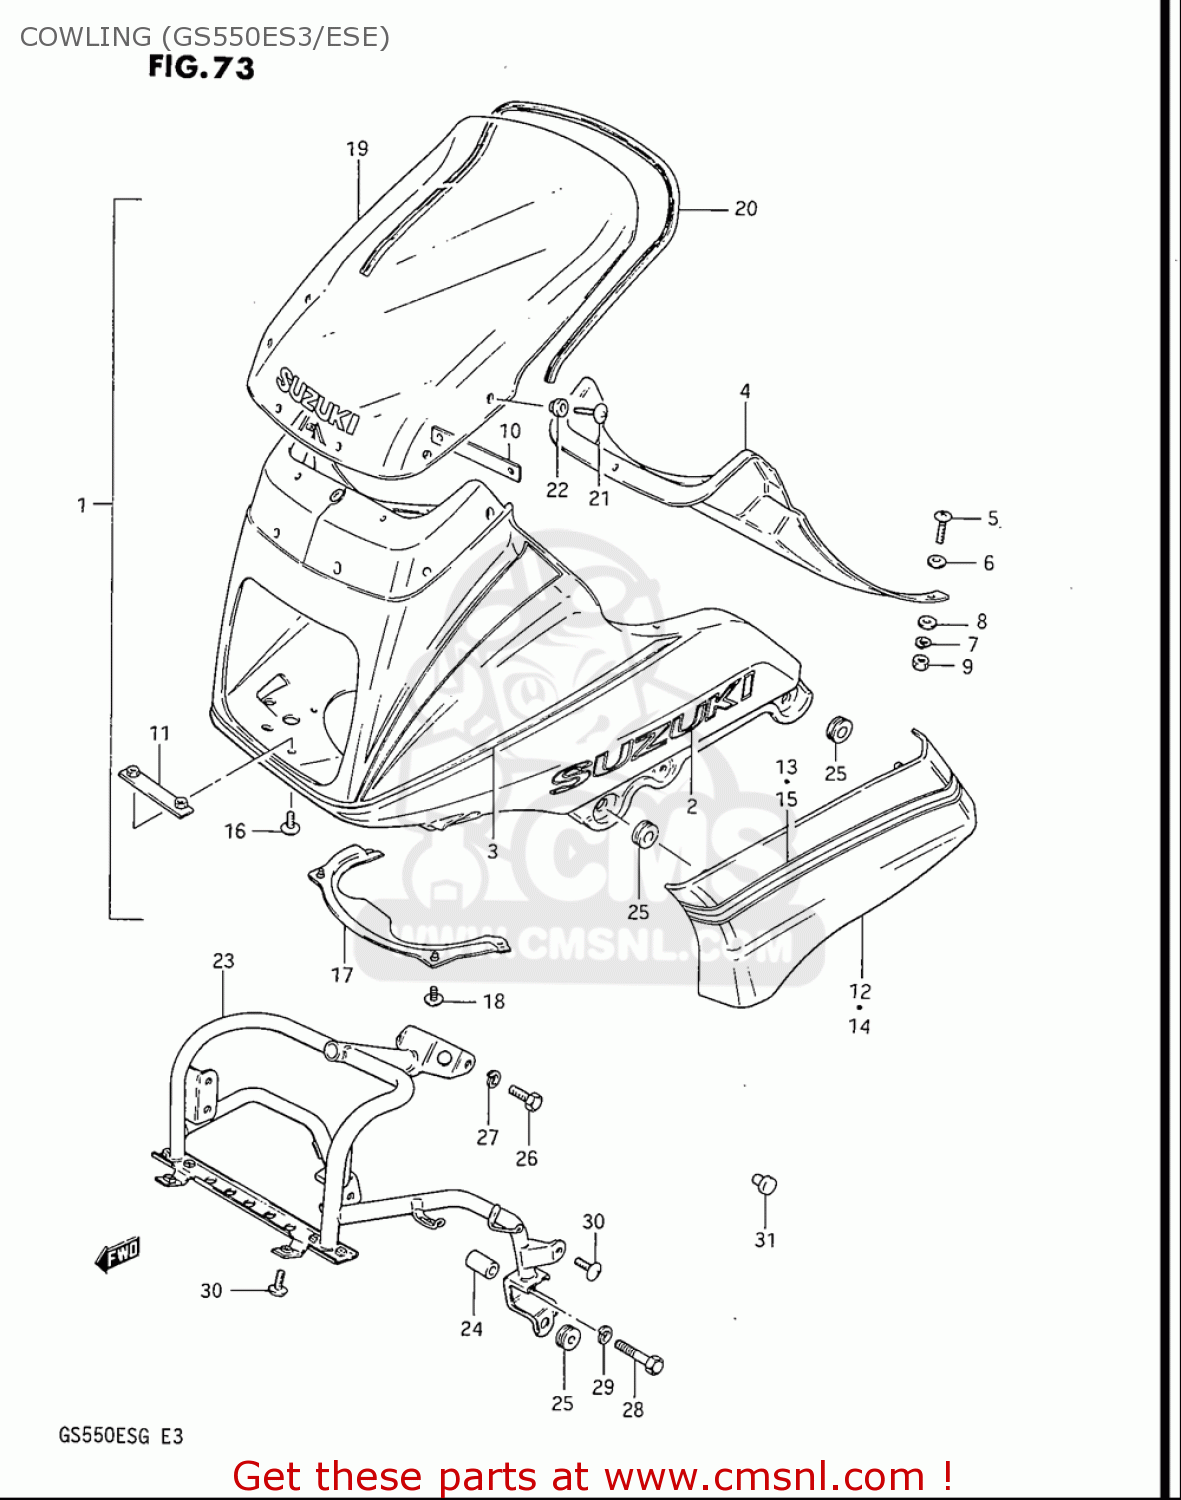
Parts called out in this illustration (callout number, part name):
2	EMBLEM,FUEL TANK
5	SCREW
6	WASHER
7	LOCK,WASHER
8	WASHER
9	NUT
12	COVER,COWLING,RIGHT
16	SCREW
18	SCREW
19	WINDOW,COWLING
20	MOLD,COWLING
21	SCREW
22	CUSHION
24	SPACER (8.2X12.5X23.5)
25	CUSHION
26	BOLT
27	WASHER,LOCK
28	BOLT
29	WASHER,LOCK
30	SCREW
31	CAP
